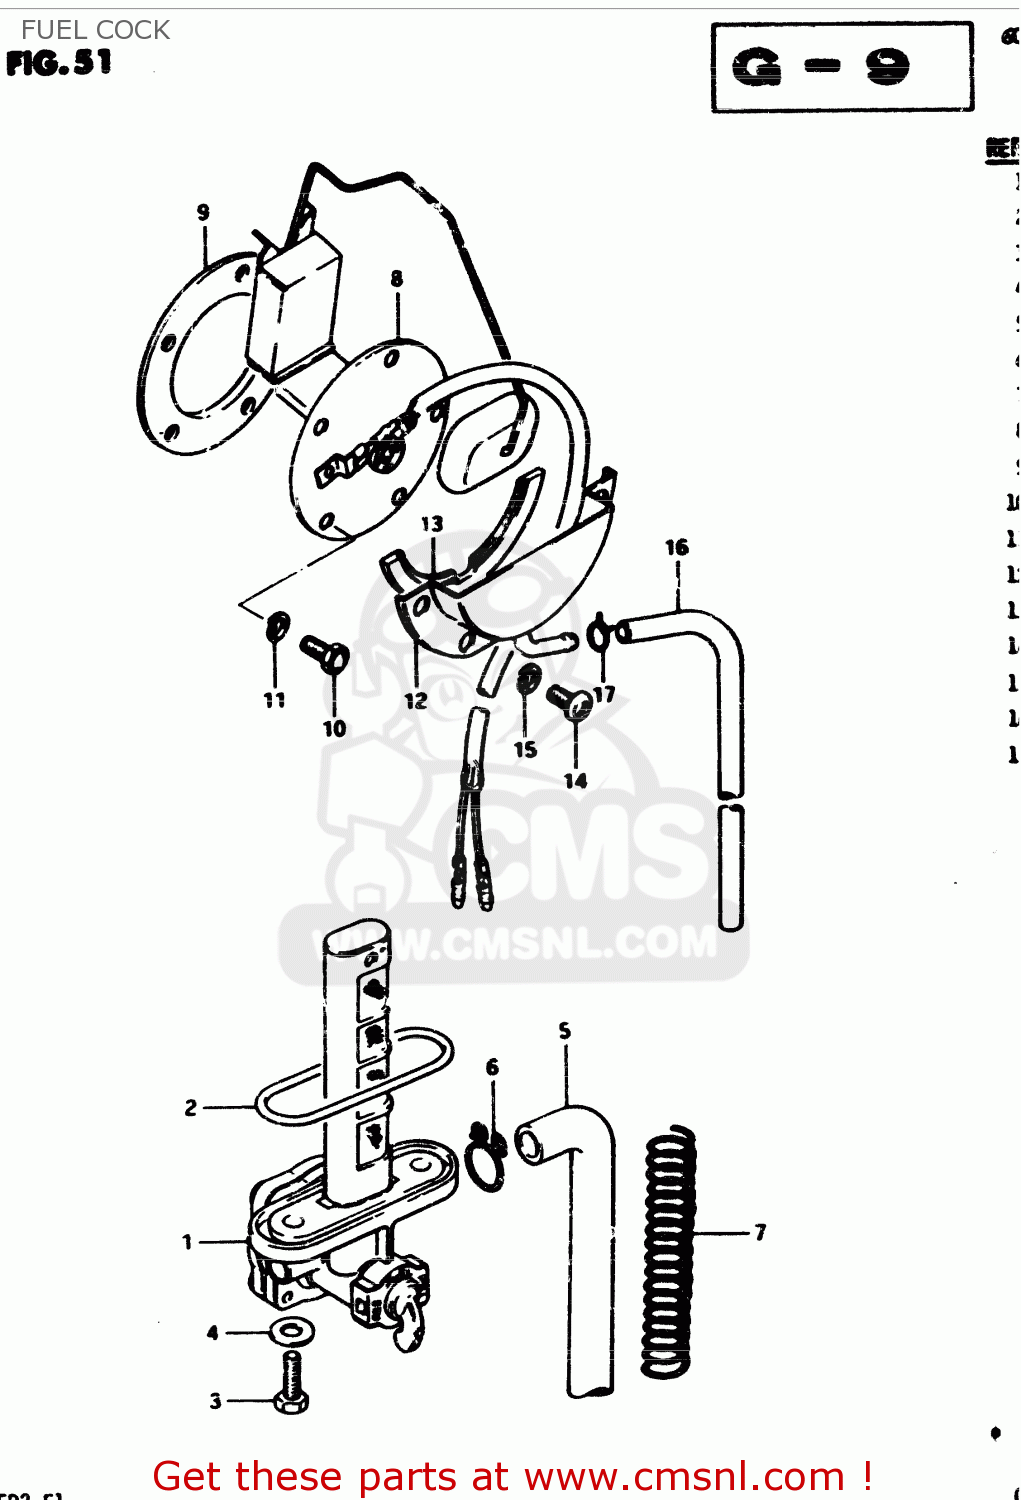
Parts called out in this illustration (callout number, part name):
1	COCK ASSEMBLY,FUEL
2	O RING
3	SCREW
4	GASKET
5	HOSE
6	CLIP
7	SPRING
8	GAUGE ASSEMBLY,FUEL LEVEL
9	GASKET,FUEL LEVEL GAUGE (NAS)
10	BOLT
11	LOCK WASHER
12	PLATE,FUEL DRAIN
13	GASKET (NAS)
14	SCREW
15	LOCK WASHER
16	HOSE,FUEL
17	CLIP
